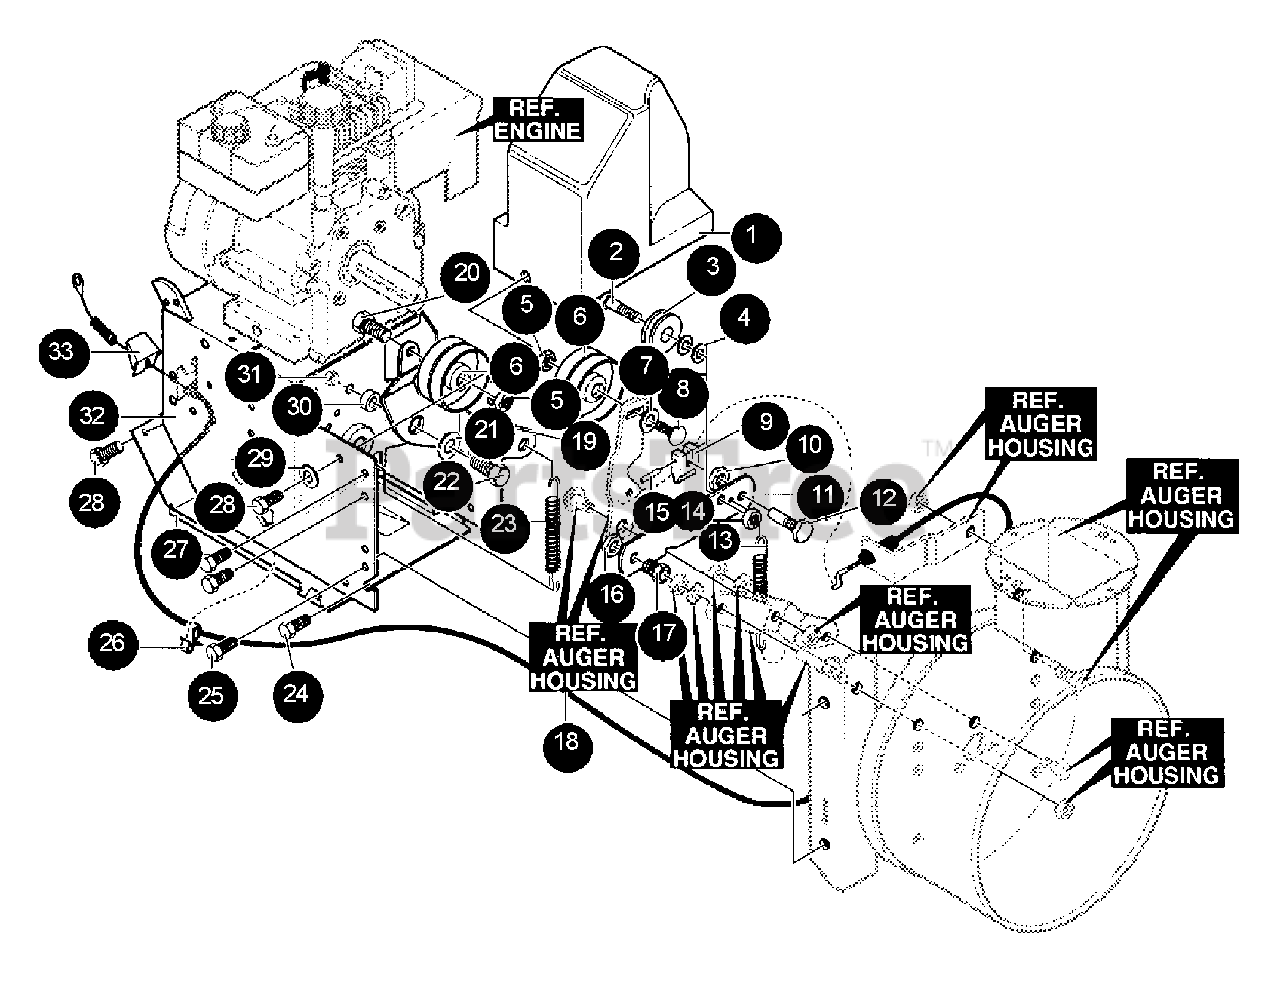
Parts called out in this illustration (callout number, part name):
1	BELT COVER KIT
2	BOLT - 0.375×0.375 HHSH 1/4-20
3	PULLEY
4	WASHER
5	LOCKNUT - 3/8-16
6	PULLEY, IDLER
7	WASHER - 0.506×0.75×0.024"
8	BOLT, 3/8-16×1.25 CARR
9	PAD, AUGER/IMPELLER BRAKE
10	LOCKNUT - 1/2-20
11	BRACKET
12	BOLT, BRAKE ARM
13	SPRING, IDLER BRAKE
14	NUT, 1/4"-20
15	PIN, SPRING
16	NUT, 9/16-18 JAMCTRLK
17	BOLT, BRAKE ARM 9/16-18
18	CABLE, AUGER
19	LEVER, IDLER ARM TRACTION
20	SCREW - 3/8-16×1.25" -- HEX HEAD CAP
21	WASHER, FLAT 0.328×1.25×0.075
22	SCREW 5/16"-18×0.75
23	SPRING, IDLER
24	SCREW 1/4"-20×0.63
25	SCREW, 5/16-18×0.50 WAHHTAP
26	CLIP, CABLE TINN #D98281-017
27	COVER, BOTTOM
28	SCREW 1/4"-20×0.63
29	WASHER
30	BUSHING, IDLER LEVER
31	NUT, 5/16 - 18
32	FRAME ASSY
33	SHIELD, CABLE GUARD
